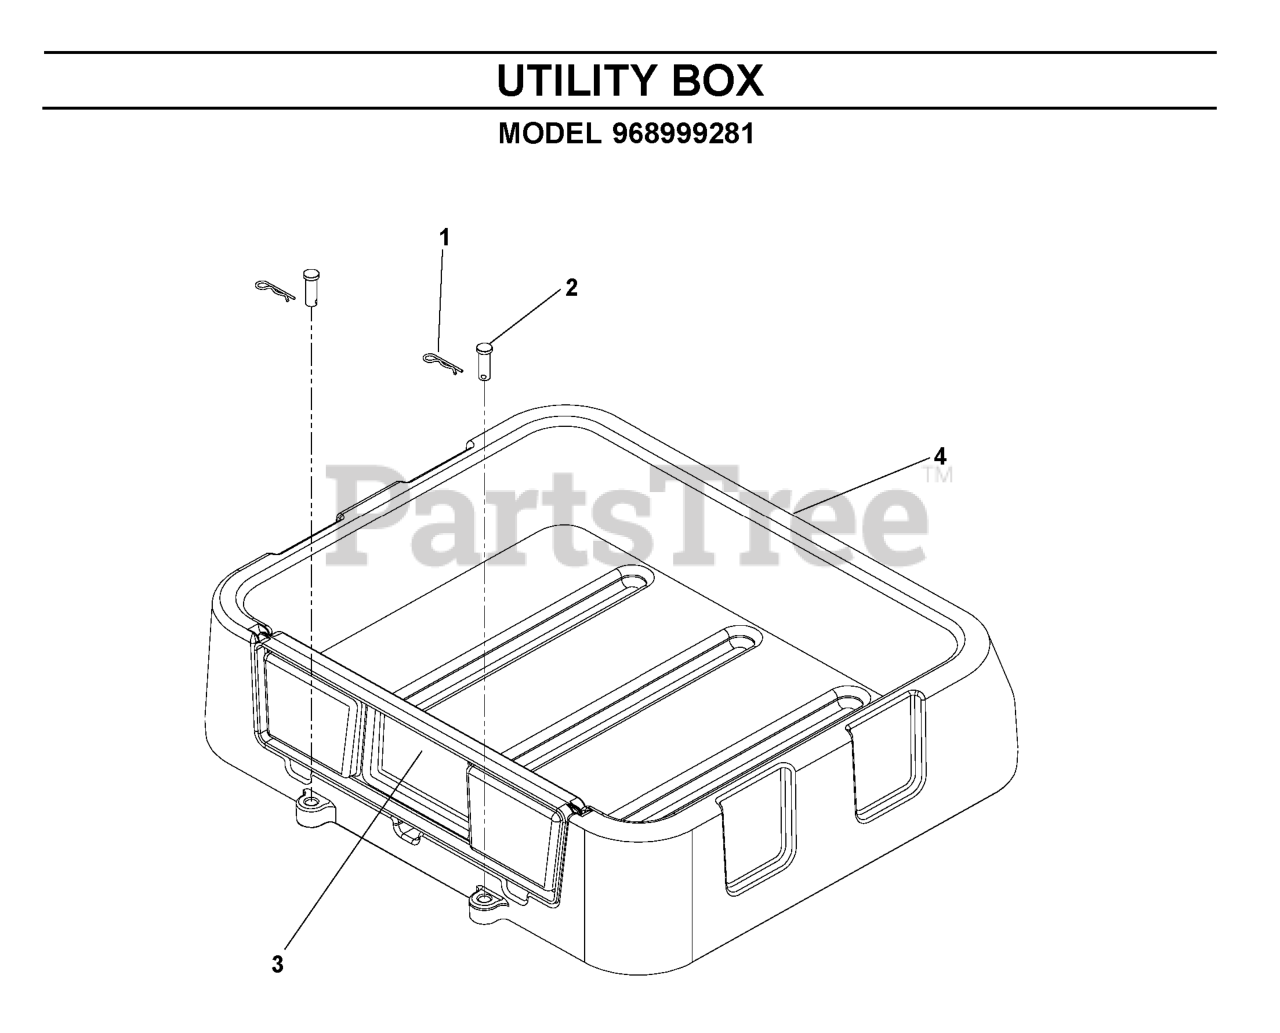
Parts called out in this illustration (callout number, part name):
1	HAIRPIN #2
2	CLEVIS PIN 3/8 X 1 1/8
4	UTILITY BOX
